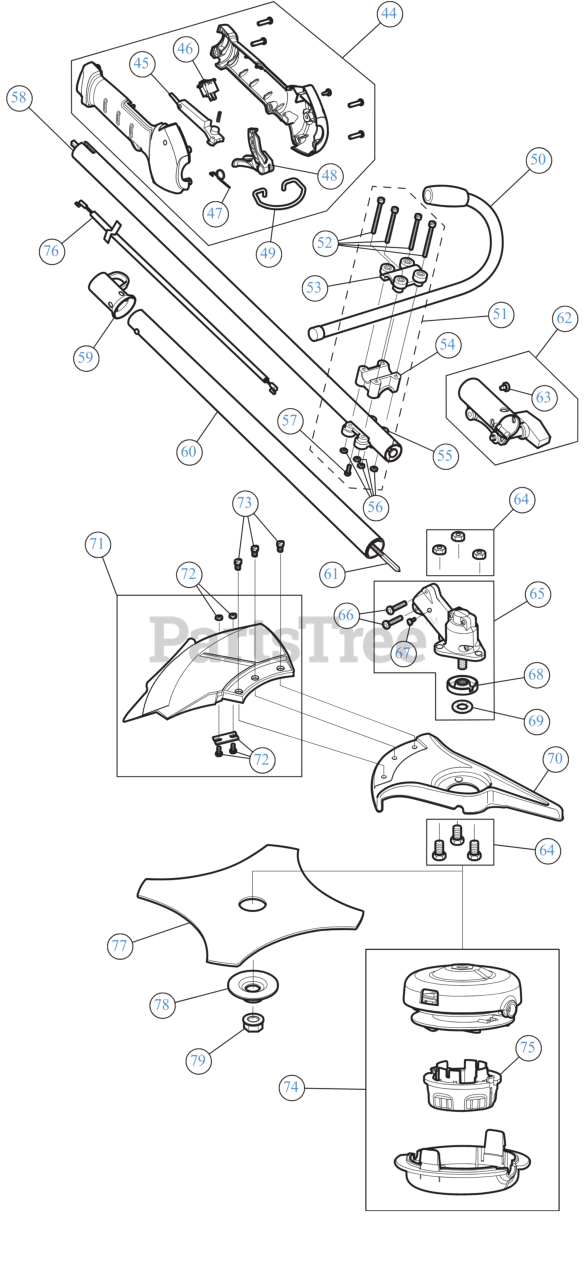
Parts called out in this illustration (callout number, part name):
44	THROTTLE GRIP ASM
45	LEVER LOCK OUT
46	SW, MOMENTARY ON/O
47	SPRING TRIG
48	THROTTLE TRIGGER
49	SHOULDER STRAP CLIP
50	HANDLE ASSEMBLY-JAY
51	HANDLE BRACKET ASSEMBLY
52	CLAMP SCREW
53	HANDLE UPPER CLAMP
54	HANDLE MIDDLE CLAMP
55	HANDLE LOWER CLAMP
57	SCREW, 8-32 x .312 P
60	BOOM ASSEMBLY LOWER
61	LOWER DRIVE SHAFT
62	SPLIT BOOM COUPLER KIT
63	SCREW, 10-32X.250 TA
64	SCREW SET-GUARD MT
65	GEARBOX ASSEMBLY
67	SCREW, 8-32 x .312 P
68	SPACER-GEARBOX
69	PALNUT:3/8" DIAM
70	SHIELD-BLADE CAST
71	SHIELD ASSEMBLY WITH BLADE
72	BLADE ASSEMBLY
73	SCREW-GUARD MTG PK
74	HEAD ASSEMBLY
76	THROTTLE CABLE
77	BLADE 4-TOOTH
78	WASHER-BLADE CLAMP BRUSH CUT
79	BLADE LOCK NUT
